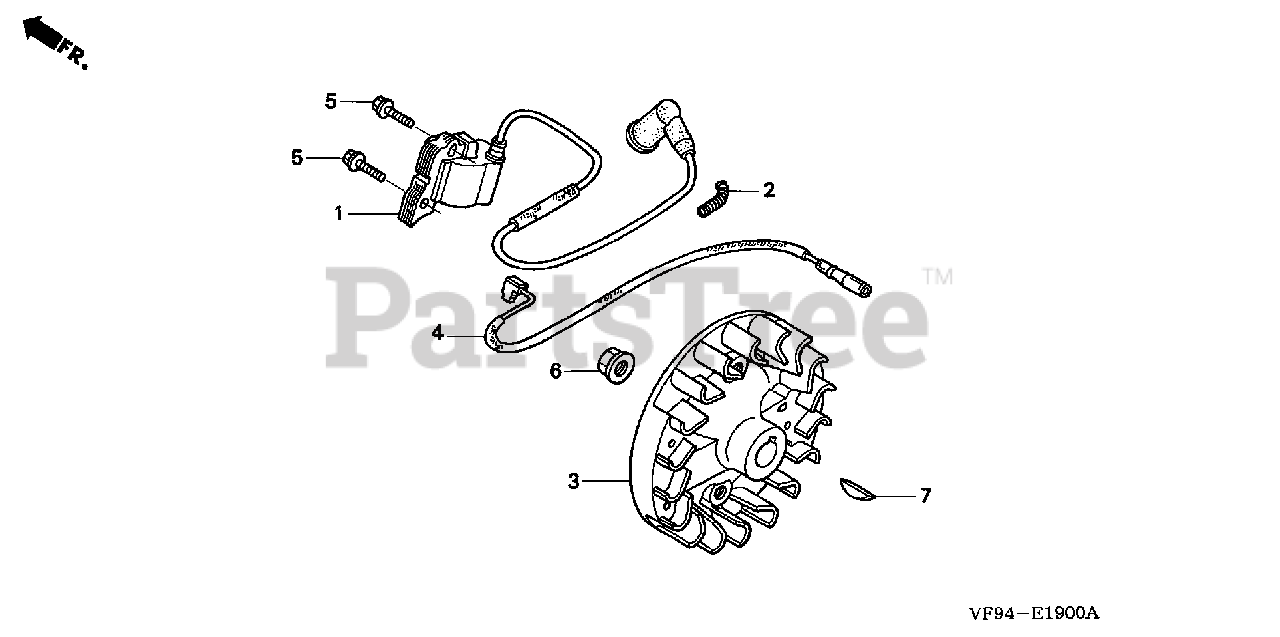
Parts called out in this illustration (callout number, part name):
1	COIL ASSY., IGNITION
2	TUBE A, CORRUGATED (7X18)
4	WIRE, STOP SWITCH
5	BOLT-WASHER (5X16)
6	NUT, FLANGE (10MM)
7	KEY, WOODRUFF (16X12)
